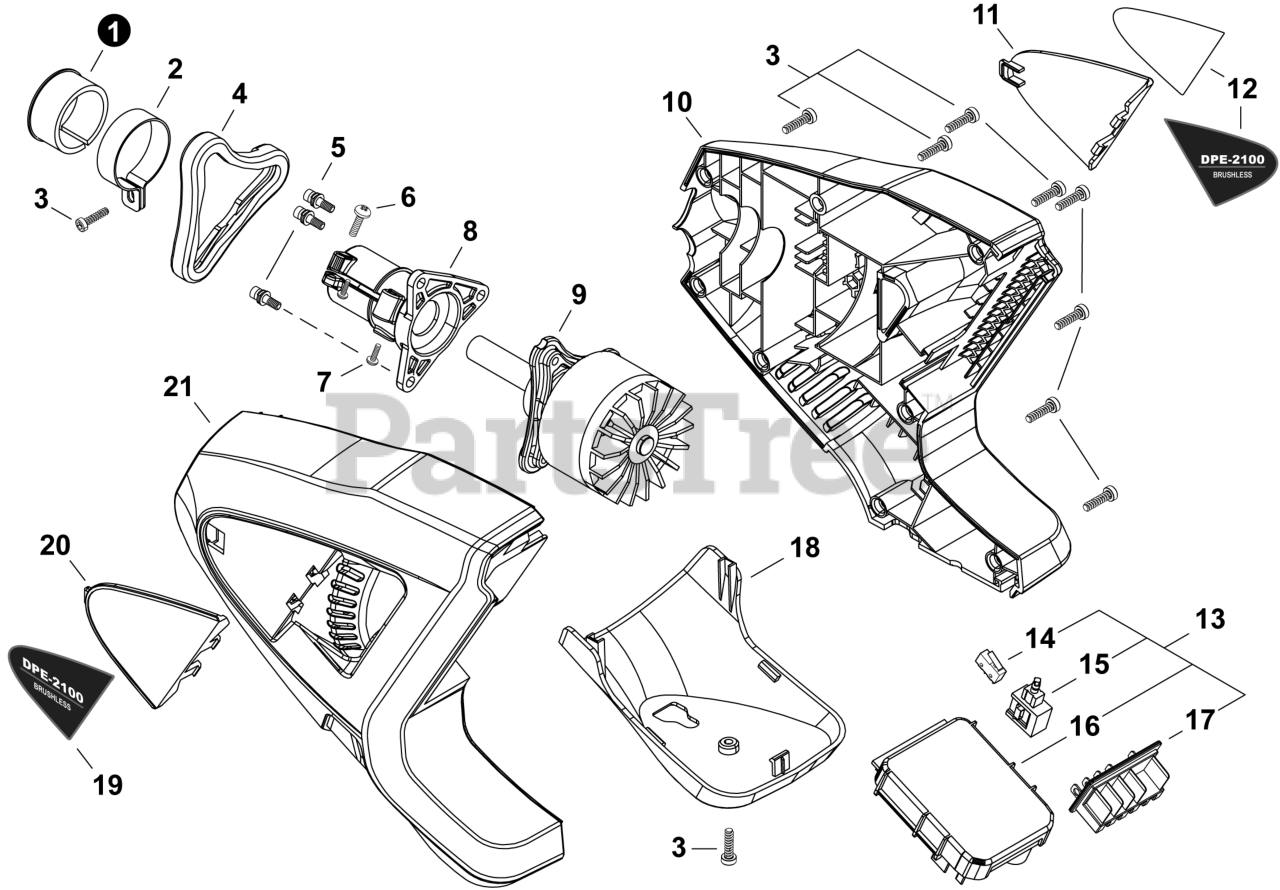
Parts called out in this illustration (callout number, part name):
3	SCREW - 4x16
5	SCREW - 5x15
6	SCREW - 4x16
7	SCREW - 5x8
8	COUPLER
9	MOTOR ASSY
10	COVER, MOTOR - RIGHT
11	PIECE, COVER - RIGHT
12	LABEL - MODEL DPE-2100 - RIGHT
13	CONTROL CABLE ASSY
14	SWITCH, HIGH/LOW MICRO
15	SWITCH, VARIABLE SPEED
16	PCBA (PRINTED CIRCUIT BOARD ASSEMBLY)
17	TERMINAL BLOCK, BATTERY
19	LABEL - MODEL DPE-2100 - LEFT
20	PIECE, COVER - LEFT
21	COVER, MOTOR - LEFT
